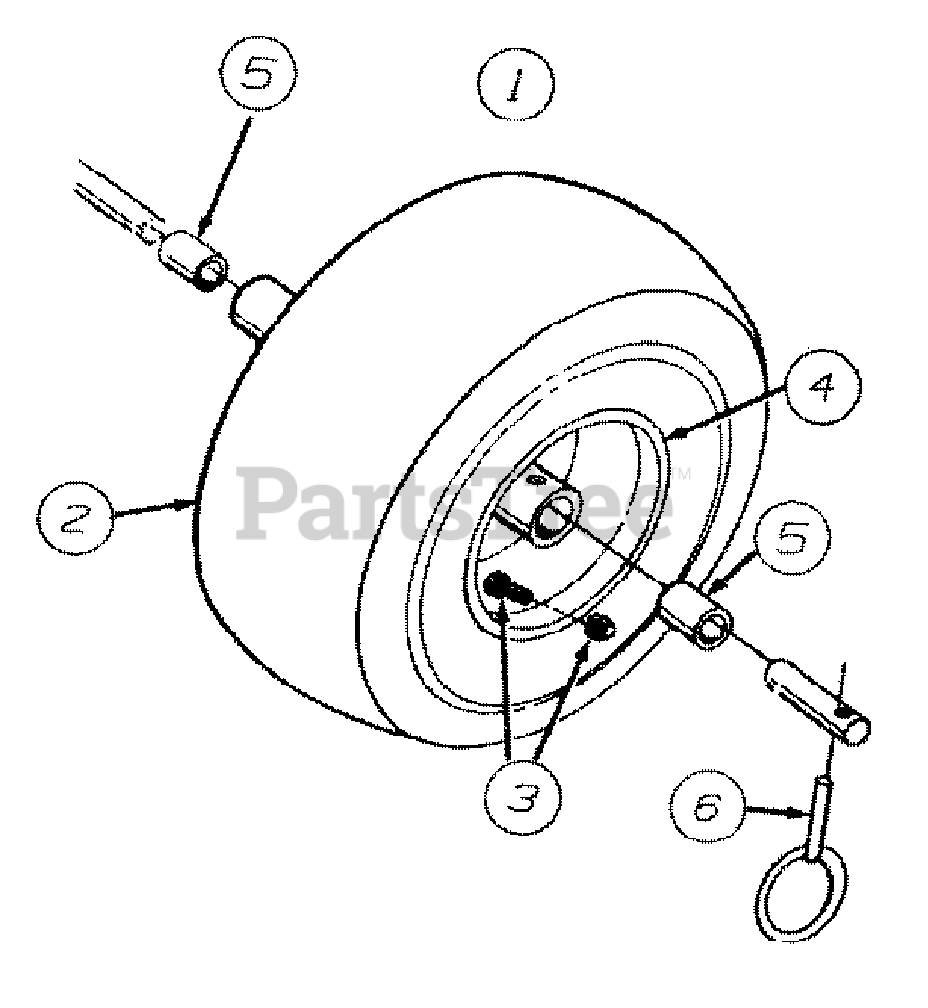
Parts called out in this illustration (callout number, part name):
1	Wheel Ass'y Complete 16 x 4.8
3	Air Valve
4	Rim Only
5	Sleeve Bearing
6	Klick Pin
